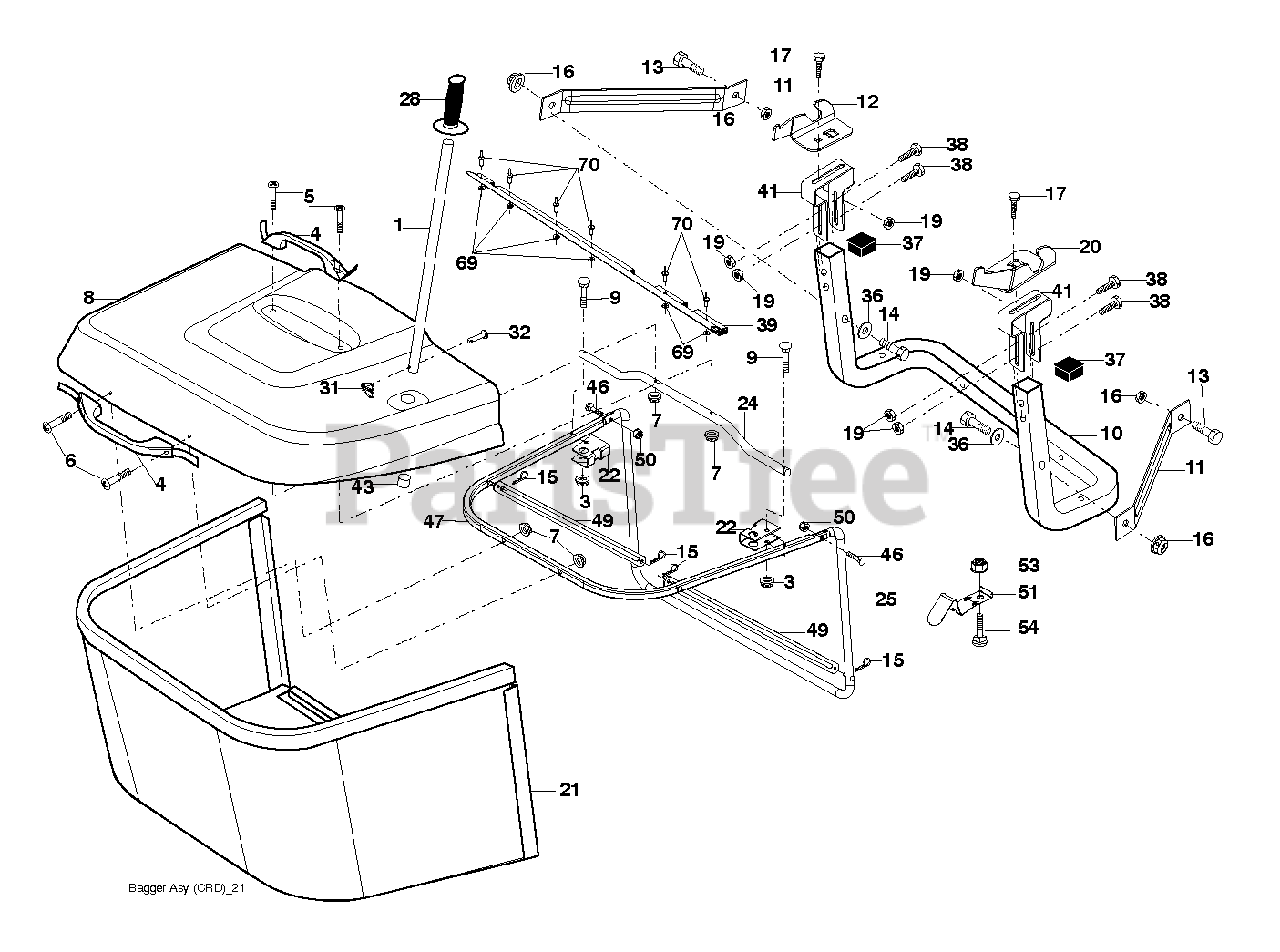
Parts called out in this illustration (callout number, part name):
1	TUBE.PNT.HDL.BAGGER.
3	NUT T
5	SCREW.PAN.HEAD
8	Bagger Cover and Seal Assembly, CRD 505
11	BRACKET
14	BOLT-HEX EAK
15	RETAINER-SPRNG RB
16	NUT LOCK FLG 3/8-16 UNC
17	BOLT
19	NUT LOCK HEX FLANGE 5/16-18
20	BRKT.PIVOT.RH.CRD
21	BAGGER.ASM.CRD.2007
22	BRACKET.BAGGER.SD.
24	TUBE
28	GRIP.HANDLE.BLACK
31	RETAINER CLIP
32	RIVET,DRILLED
38	BOLT.5/16-18X2.5
39	SEAL.BAGGER.CRD
41	BRACKET.BAGGER.SD.
43	PLUG, TUBING END
46	BOLT.CARRIAGE.5/16-18
50	NUT.71038.31-18.HEX.NYLOCK
53	NUT
54	BOLT
